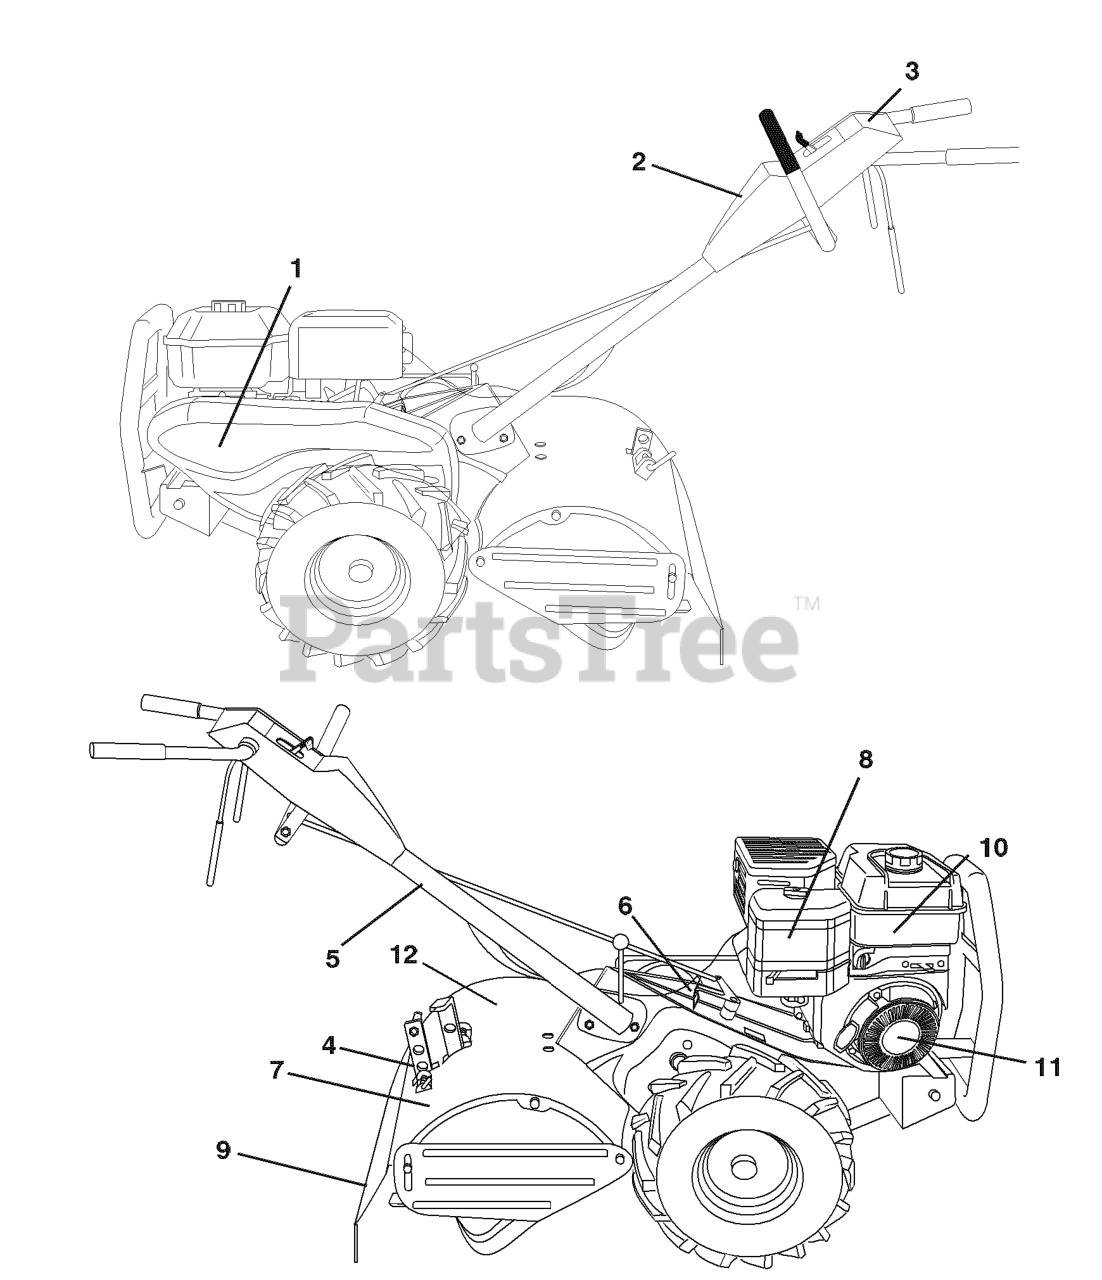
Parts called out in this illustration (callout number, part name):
1	DECAL.BLTGRD.900DRT.HUSQ
2	DECAL.CONSOLE.700DRT.HUSQ
3	DECAL.CONSOLE.DRT.HU
4	DECAL.SHIELD.TN.DRT17.HUSQ.008
5	DECAL TI (2 2)
6	DECAL.SHIFT.INDICATOR.DRT
7	DECAL.REVERSE.HUSQ
8	DECAL.B&S.900.A/C.REF.277024
9	DECAL.DRT.WARN.ENG/F
10	DECAL.B&S.900.TANK.REF.276991
11	DECAL, REWIND STARTER, B&S
12	DECAL.FORWARD.HUSQ
